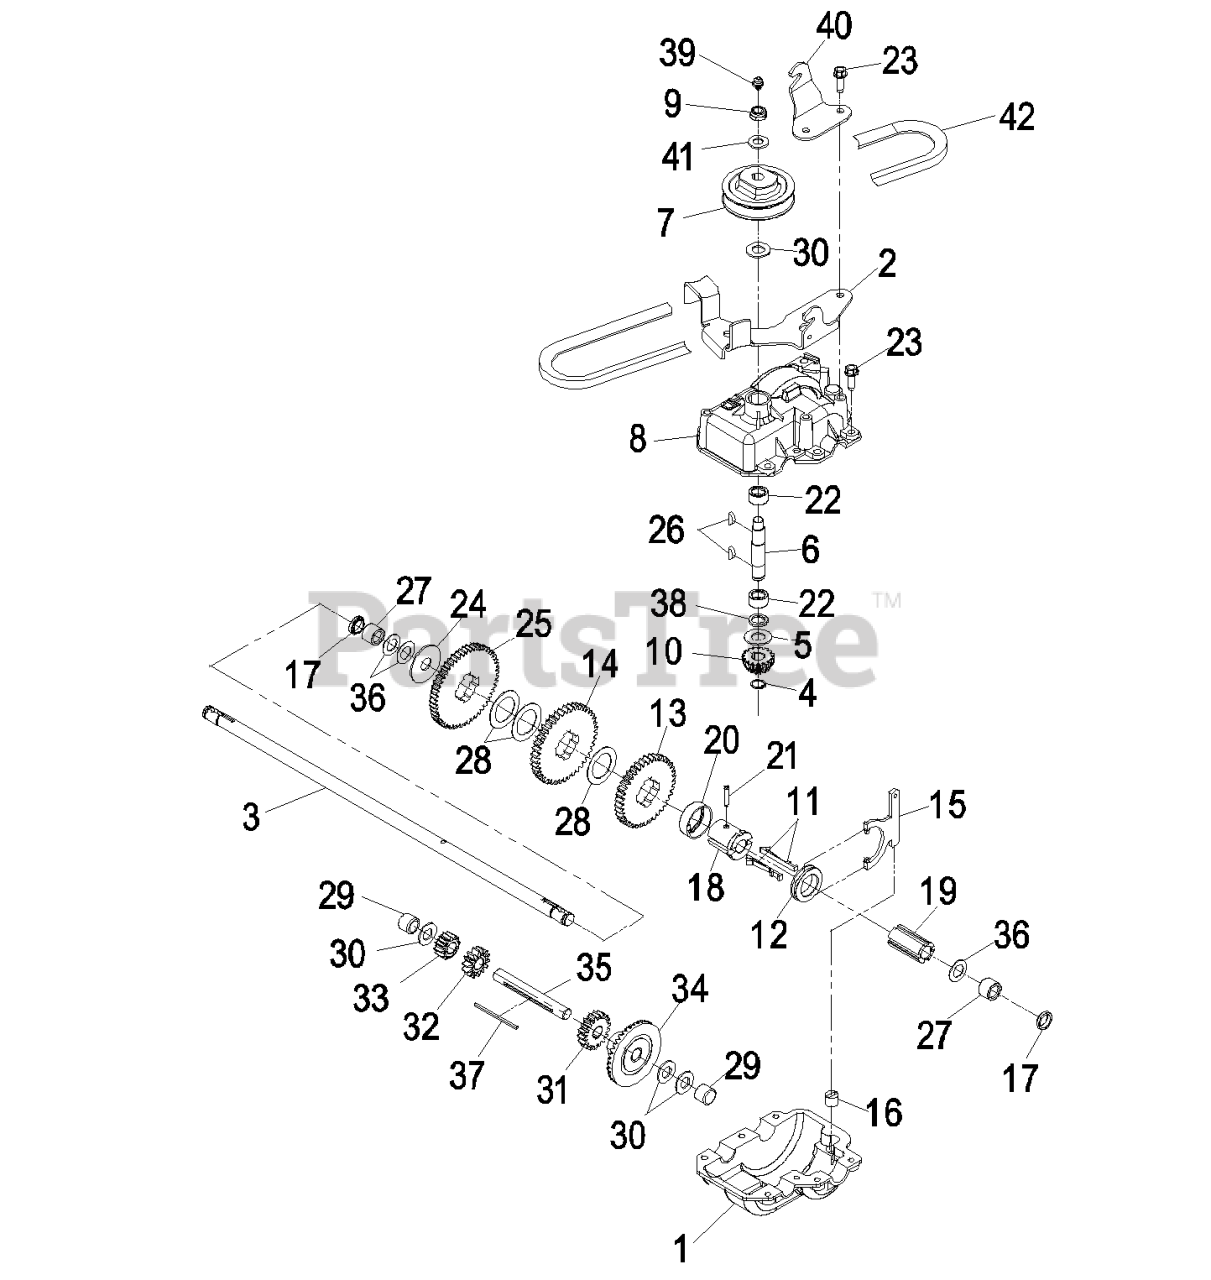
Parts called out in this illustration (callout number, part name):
2	BRACKET-GUIDE, BELT
3	SHAFT-OUTPUT
4	RING-RETAINING
5	WASHER-THRUST
9	NUT-HEX
10	PINION-BEVEL
11	KEY-SHIFT
12	COLLAR-SHIFT
13	GEAR-38T
14	GEAR-42T
15	YOKE-SHIFT
16	BUSHING-YOKE
17	SEAL-OIL
18	SLEEVE-GEAR
20	RETAINER-KEY
21	PIN-GROOVE
22	BEARING-NEEDLE
23	SCREW-HWHTF
26	KEY-WOODRUFF
29	BEARING-NEEDLE, CLOSED
30	WASHER-THRUST
31	GEAR-18T
32	GEAR-14T
33	GEAR-12T
34	GEAR-BEVEL
35	SHAFT-INTERMEDIATE
36	WASHER-PLAIN
39	FITTING-GREASE, ZERK
40	BRACKET-ENGAGE, TRACTION
41	WASHER-FLAT
42	V-BELT
